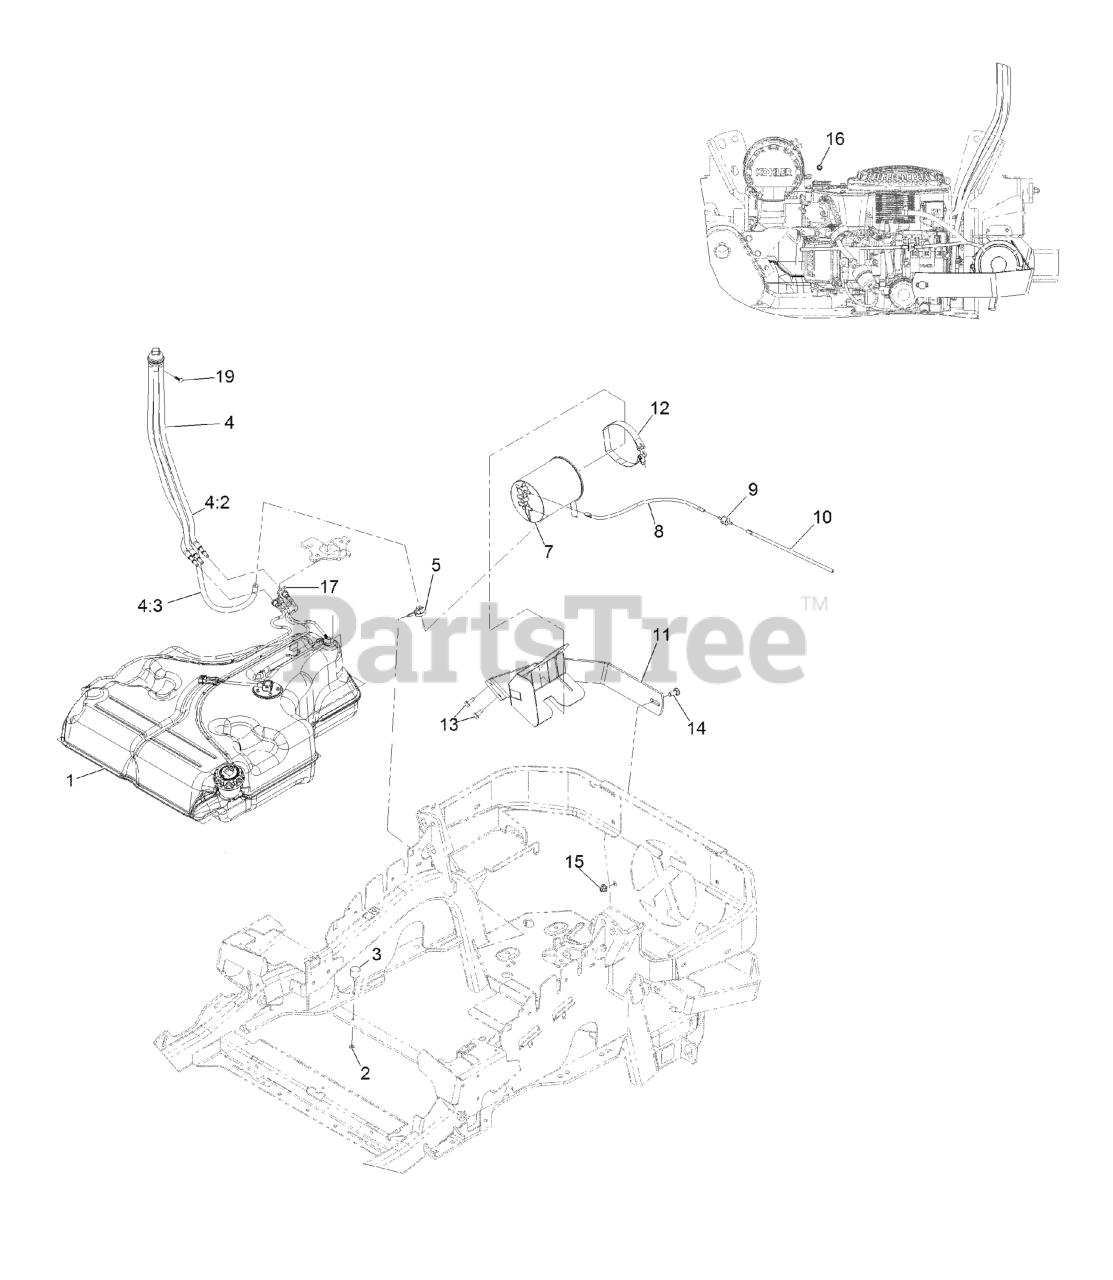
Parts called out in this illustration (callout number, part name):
1	FUEL TANK ASM
2	NUT-JAM
4	FUEL MANIFOLD VENT ASM
4:2	HOSE-FUEL
4:3	HOSE-FUEL
5	CLAMP-HOSE
7	CANISTER-CARBON, 1200CC
8	HOSE-VENT, FORMED
9	VALVE-CHECK, VACUUM
10	HOSE-VENT, FORMED
11	MOUNT-CANISTER
12	CLAMP, T-BOLT
13	Screw-HWH 5/16-18 X 3/4 Tf
14	SCREW-CARR
15	NUT-HF, NI
16	PLUG-PORT
17	RETAINER-LINE, VAPOR
19	PLUG-PLASTIC
